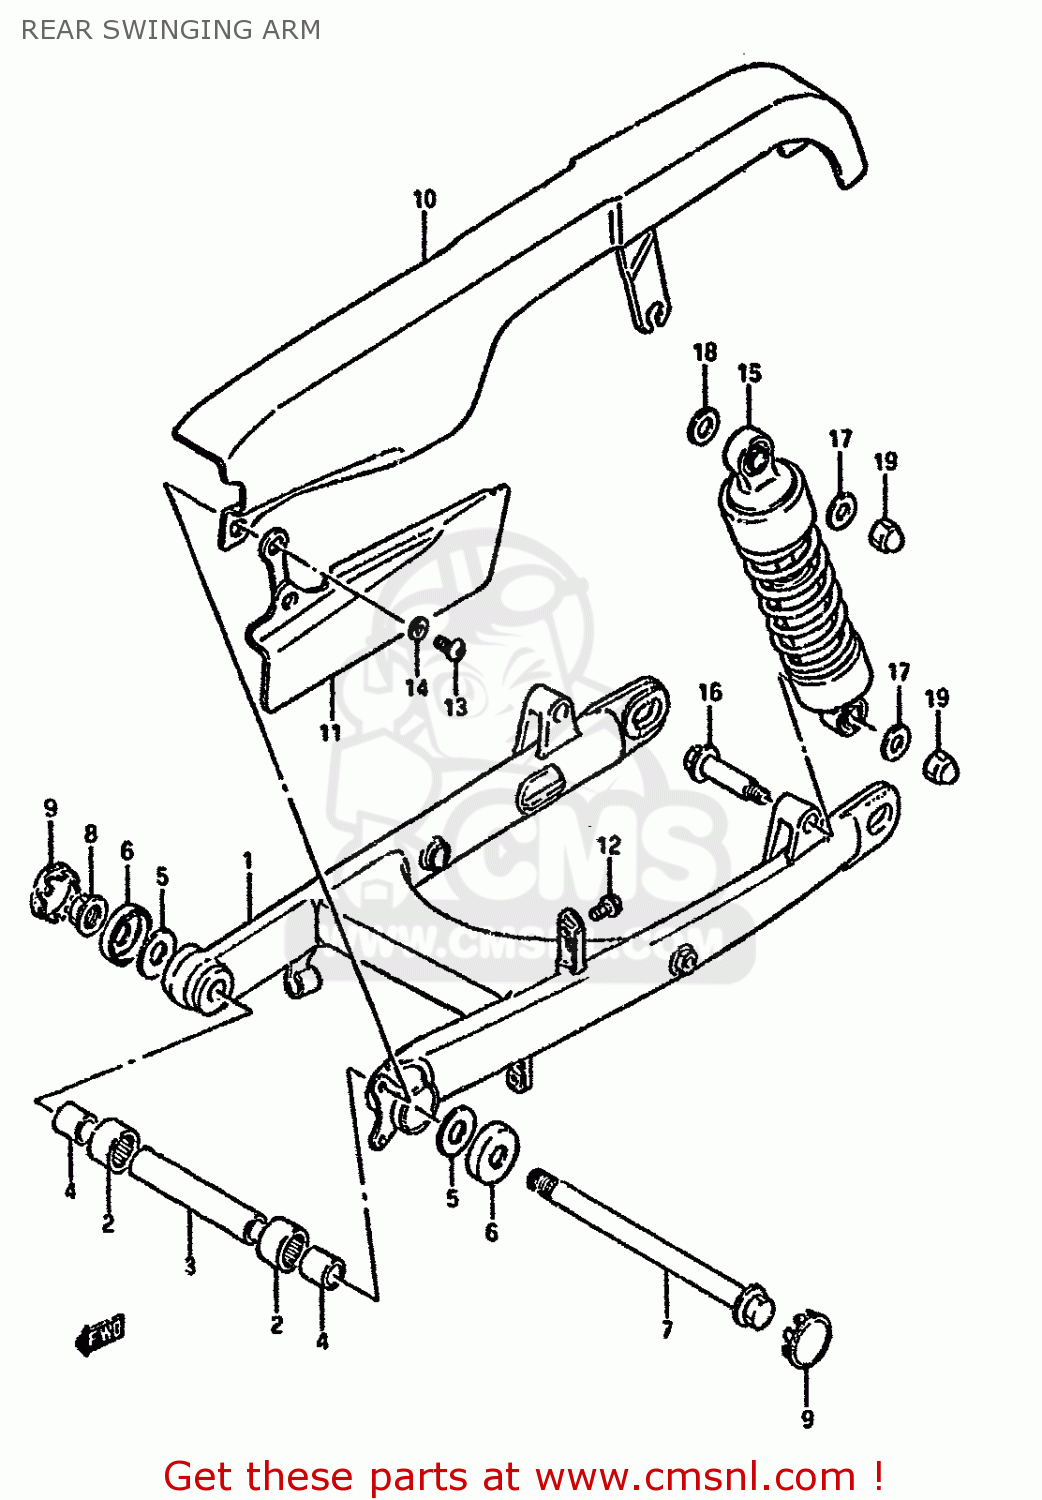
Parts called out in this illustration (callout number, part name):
1	SWING ARM,REAR
2	BEARING(22X29X30)
3	SPACER,RR SWGARM PIVOT CTR
4	SPACER,RR SWGARM PIVOT
5	WASHER
6	CVR,RR SWGARM DUST SEAL(OD:40)
7	SHAFT,RR SWINGINGARM PIVOT
8	NUT
9	CAP,RR SWINGING ARM PIVOT,R
10	BELT CASE,UPR
11	BELT CASE,LWR
12	BOLT
13	SCREW
14	WASHER
15	ABSORBER ASSY,RR SHOCK
16	BOLT,RR SHOCK ABSORBER LWR
17	WASHER
18	WASHER(14.5X29X2.3)
19	NUT
